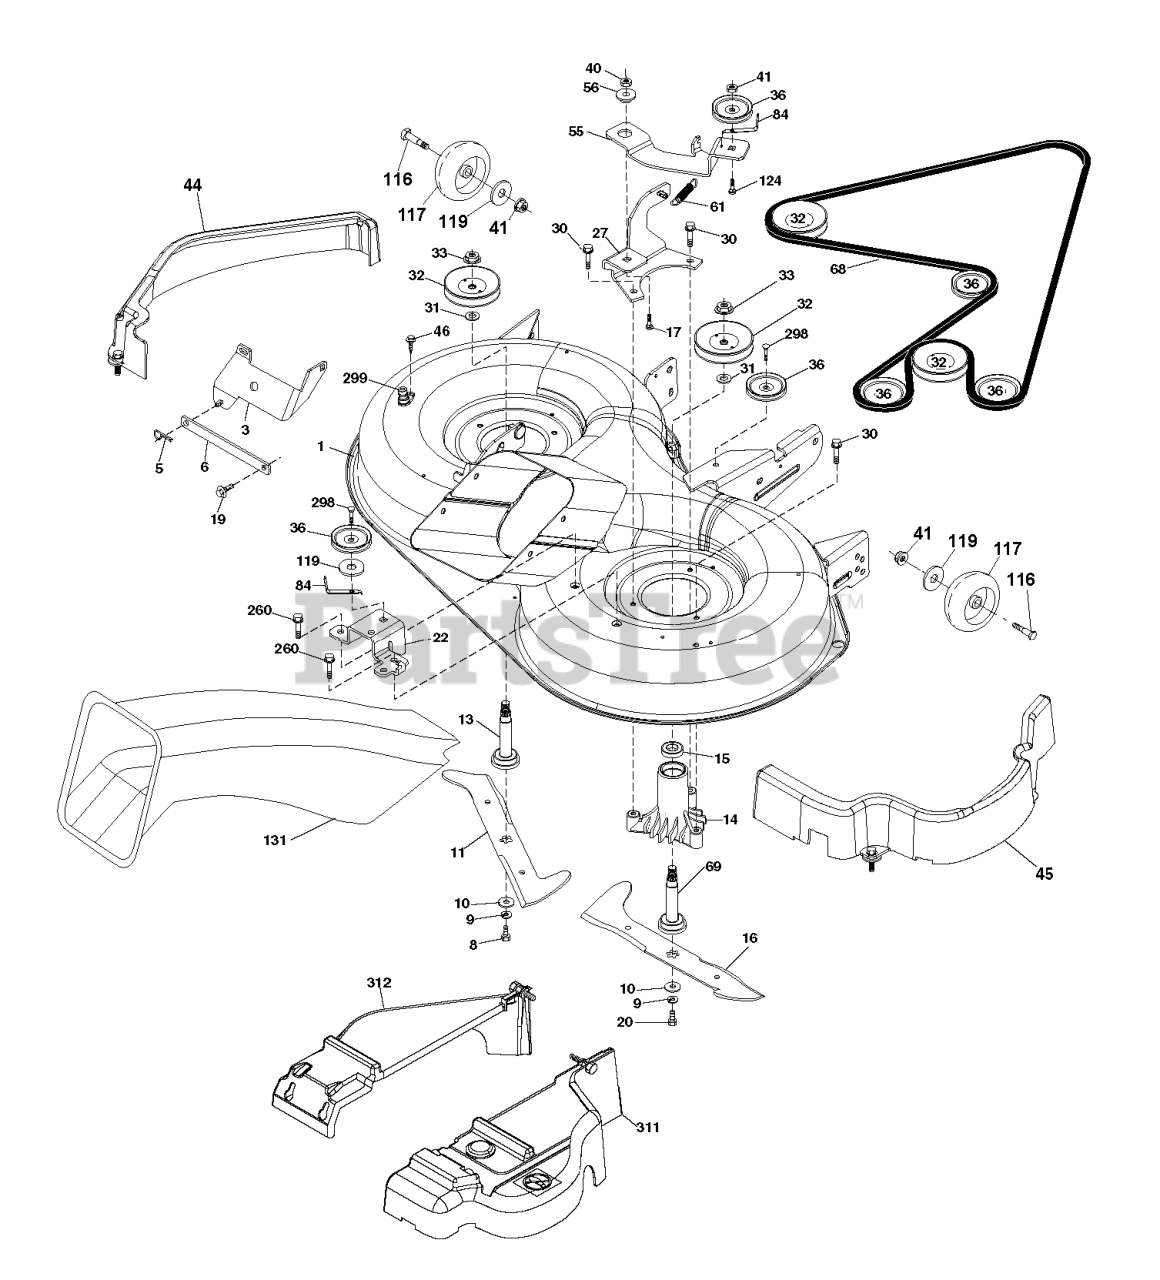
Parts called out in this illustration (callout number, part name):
1	DECK.WLDT.97.CRD.2GWB.
3	BRACKET.ASM.BAR.SWAY.CHASS
5	RETAINER-SPRNG RB
6	BAR.SWAY.92.CRD
8	BOLT.3/8-24X1.25 GR8
9	LOCKWASHER
10	WASHER.BLADE
11	BLADE.3N1.LH.CRD.97
13	SHAFT ASM VENT
14	HOUSING.MANDREL.VENTED (MACHD)
16	BLADE.3N1.RH.CRD.97
17	BOLT.3/8-14X1.25
19	BOLT SHD 5/16-18
20	BOLT.3/8-24X1.25GR8. LHTHRD
22	BRACKET.SUPT.IDLER.REAR.RH
27	BRACKET.ASM.SUSP.REAR.RH.
30	SCREW, WASHER HEAD
31	WASHER.SPACER.MANDREL
32	PULLEY MANDREL
33	NUT.FLANGE.LOCK.TOP
36	PULLEY.IDLER.4.25
41	NUT LOCK FLG 3/8-16 UNC
44	COVER MANDREL LEFT
45	COVER MANDREL RIGHT
46	SCREW.1/4-20X5/8
55	ARM.IDLER.92 CRD.2006
56	SPACER.RETAINER.MOWER
61	SPRING
68	BELT.DRIVE.CRD.97.2010
69	SHAFT.ASM.W/LWR.BRG.RH.THREAD
84	KEEPER, BELT IDLER
116	BOLT.SHOULDER.3/8-16X3-5/8.
117	RP WHEEL. GUAGE RALLY
119	WASHER
124	BOLT.3/8-16X1.50
131	CHUTE BAGGER
260	SCREW 3/8-16X1/2
298	SCREW LT
299	PORT.WASHOUT
311	COVER RIGHT
312	COVER LEFT
